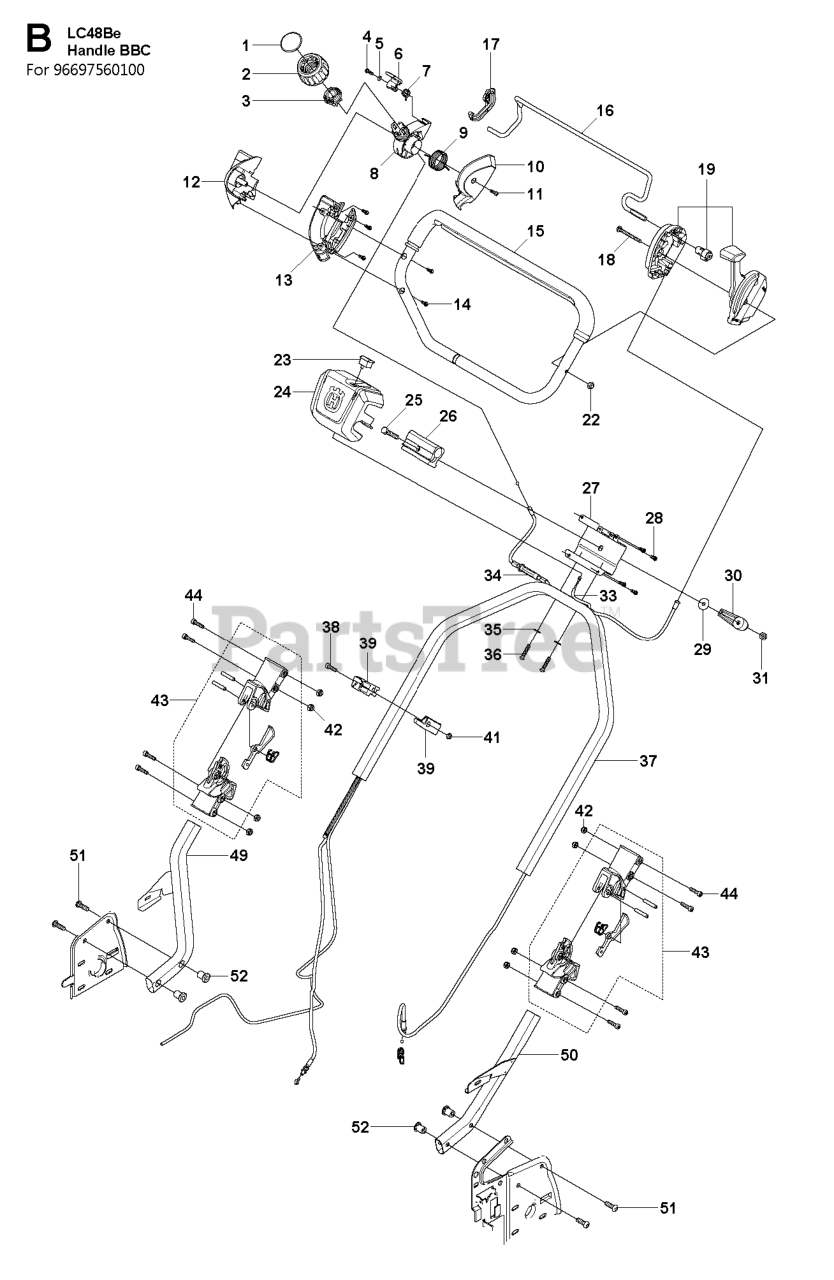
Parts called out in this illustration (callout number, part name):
5	WASHER
29	WASHER - 25X8.5X2.3
38	SCREW MC6S 6X20
44	REPL BY 725 53 74-55
